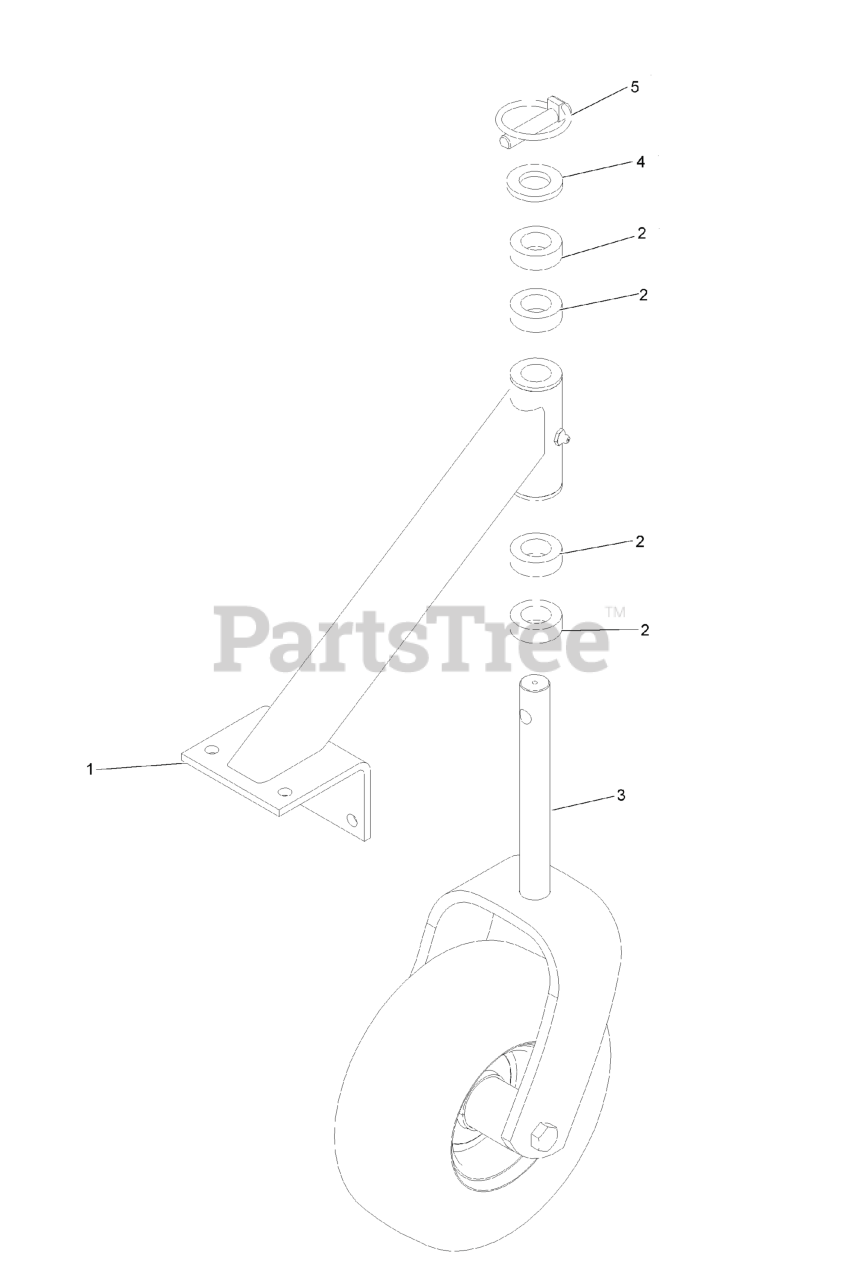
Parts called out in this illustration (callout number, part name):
1	ASM,CSTR SUPPORT W/WEIGHT
2	SPACER-CASTER
3	ASM,CASTER/WHEEL
4	WASHER-FLAT
